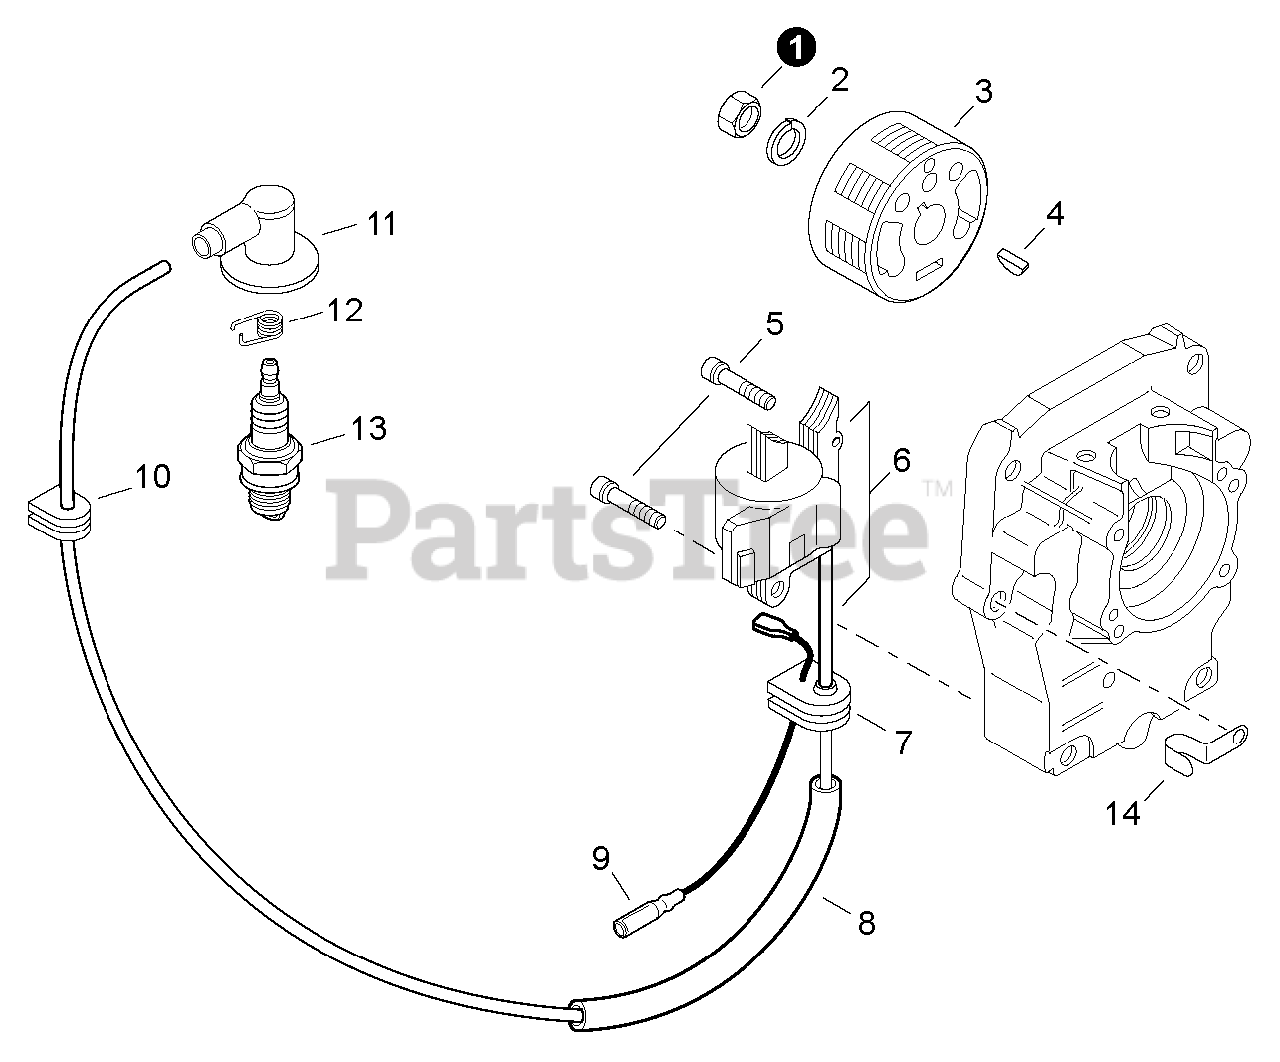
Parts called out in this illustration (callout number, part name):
1	NUT - 10
2	LOCKWASHER - 10
3	FLYWHEEL
4	KEY - 3X10
5	SCREW - 5
6	COIL, IGNITION
7	GROMMET
8	SLEEVE, INSULATOR
9	LEAD - IGNITION
10	GROMMET
11	CAP, SPARK PLUG
12	TERMINAL, SPARK PLUG CAP
13	SPARK PLUG -- BMR-6A
14	CLIP
